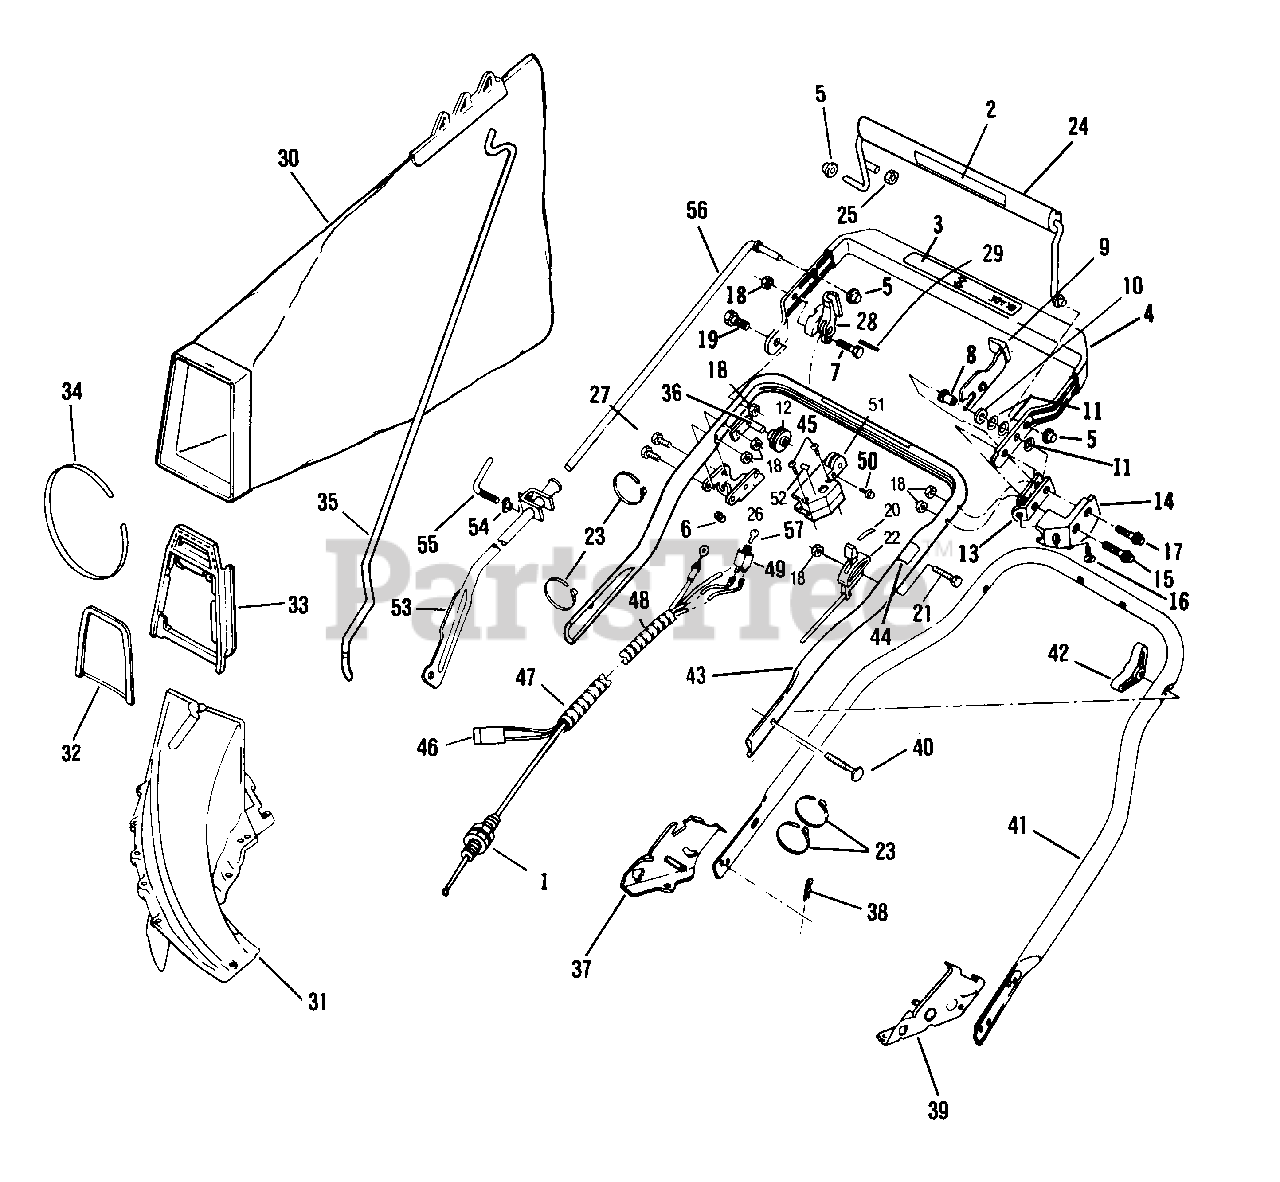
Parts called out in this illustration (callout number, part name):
1	Control Cable Assembly
2	Decal-Drive Control
3	Decal-Starting Instructions
4	Top Handle and Grip Assembly
5	Pushnut
6	Ring-Retainer
7	Bolt-Hex
8	Spacer-Flanged
9	Lever-Lockout
10	Washer-Plain
11	Washer-Spring
12	Pulley
13	Down-Stop
14	Guard-Lockout
15	Bolt-Shoulder
16	Screw
17	Bolt-Shoulder-L.H.
18	Locknut
19	Bolt-Shoulder-R.H.
20	Decal-Throttle
21	Screw-Throttle Mounting
22	Control Assembly-Throttle
23	Tie Strap
24	Control Lever and Nut Assembly
25	Nut-Acorn
26	Bracket-Clutch Cable
27	Screw-Clutch Cable Bracket
28	Cam
29	Roll Pin
30	Bag Assembly
31	Chute Assembly
32	Brace-Chute
33	Adapter-Chute
34	Strap
35	Rod-Grass Bag
36	Pivot-Bracket Pulley
37	Bracket-Handle-R.H.
38	Hair Pin
39	Bracket-Handle-L.H.
40	Screw
41	Handle Section-Bottom
42	Knob
43	Handle Section-Center
44	Decal-Drive Lockout
45	Screw
46	Wire Harness Assembly
47	Spiral Tubing
48	Spiral Tubing
49	Switch Assembly
50	Screw
51	Cover
52	Decal
53	Control Lever Assembly
54	Nut-Control Lever Clamp
55	Lever-Rod Clamp
56	Rod-Control
57	Key Switch (2)
